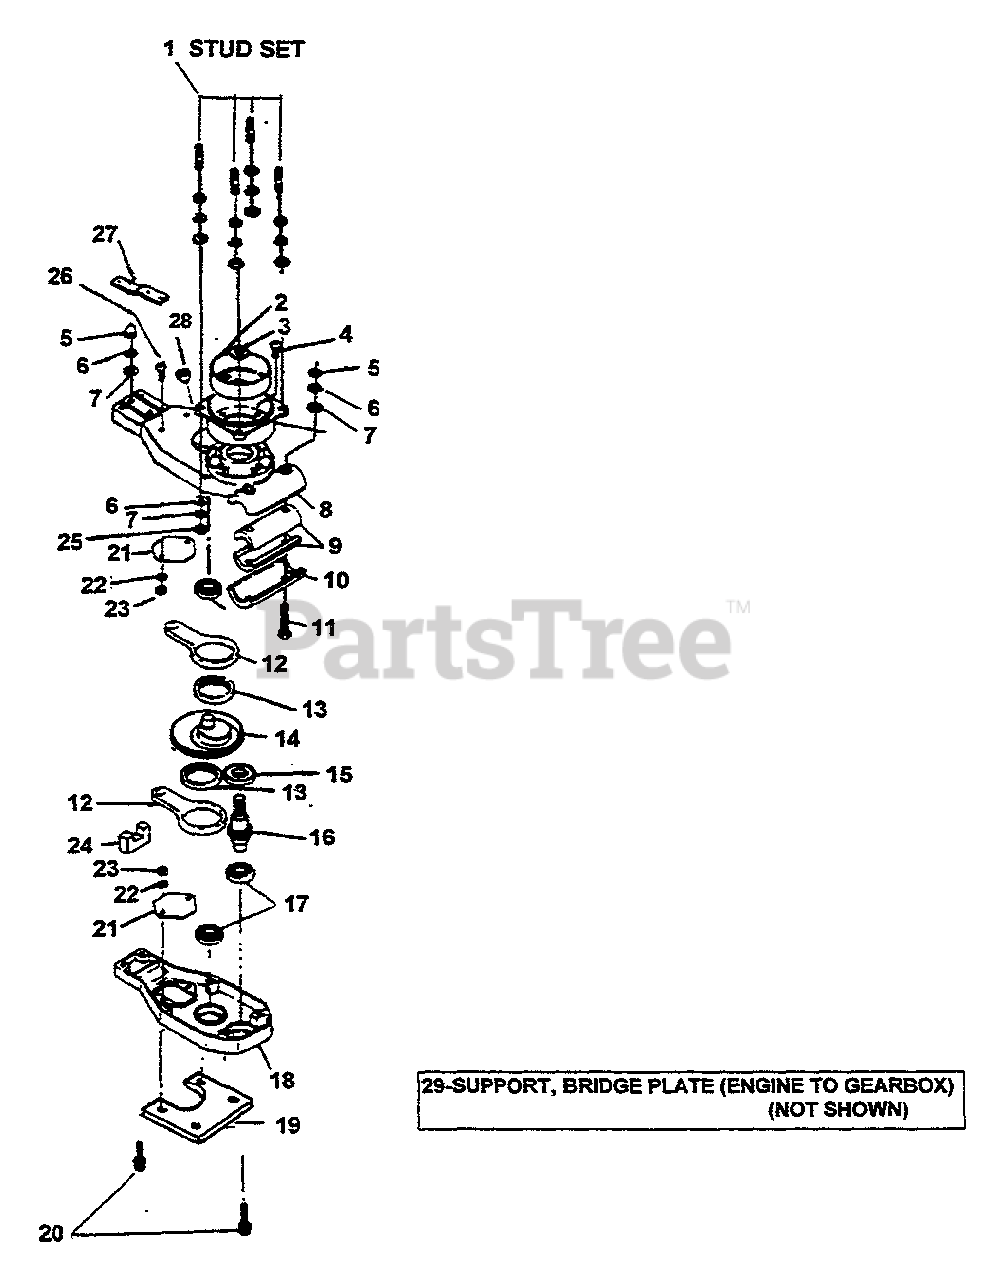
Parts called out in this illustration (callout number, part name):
2	CLUTCH DRUM
8	CASE, UPPER
9	INSERT, HANDLE RUBBER
10	BRACKET, HANDLE
12	CRANK ROD
14	CRANKSHAFT
18	CASE, LOWER
19	HANDLE SUPPORT
21	BRIDGE PLATE
24	FELT, OIL
26	GREASE FITTING
27	BLADE SUPPORT
